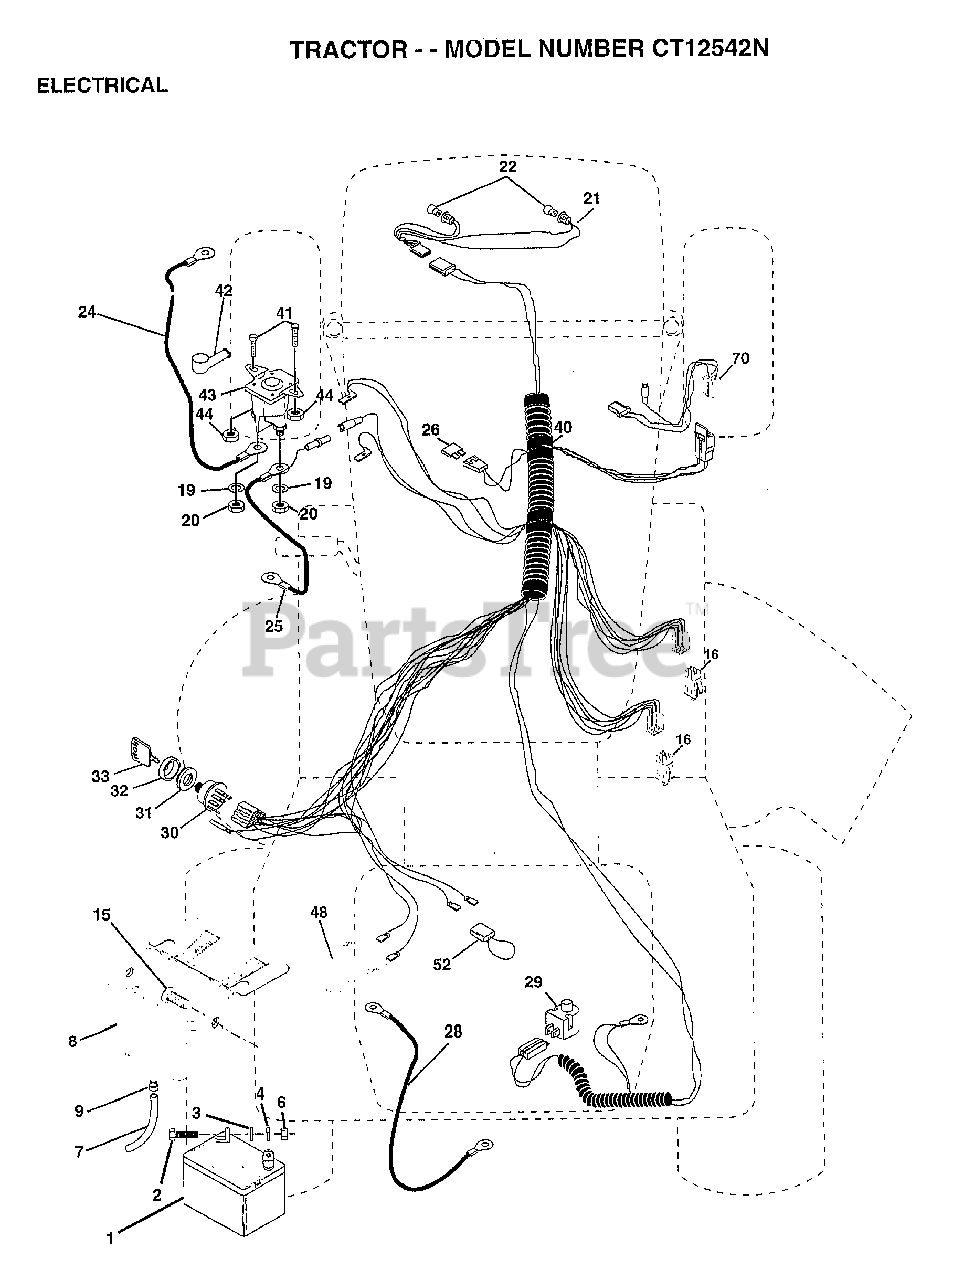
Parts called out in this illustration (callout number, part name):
2	BOLT LT
3	WASHER
4	LOCKWASHER
7	TUBE T
8	"CASE,BATTERY.MECH"
9	HOSE CLAMP T
15	FASTNER.SNAP-IN
16	SWITCH INTERLOCK
20	NUT
21	"HARNESS,LIGHT SOC"
22	HEADLAMP BULB
24	"CABLE T, BATTERY"
25	CABLE.BTRY.6GA.RD
26	FUSE HYT
28	CABLE T
29	SWITCH SEAT
30	SWITCH IGN 4POS
31	NUT IGNITION
32	COVER KEY SWITCH
33	KEY
40	HARNESS-IGNITION
41	BOLT HXHD FIN
44	NUT HXKEP 1/4X20
48	ADAPTER AMMETER
52	PROTECTION LOOP
70	HARNESS ENG DUAL
